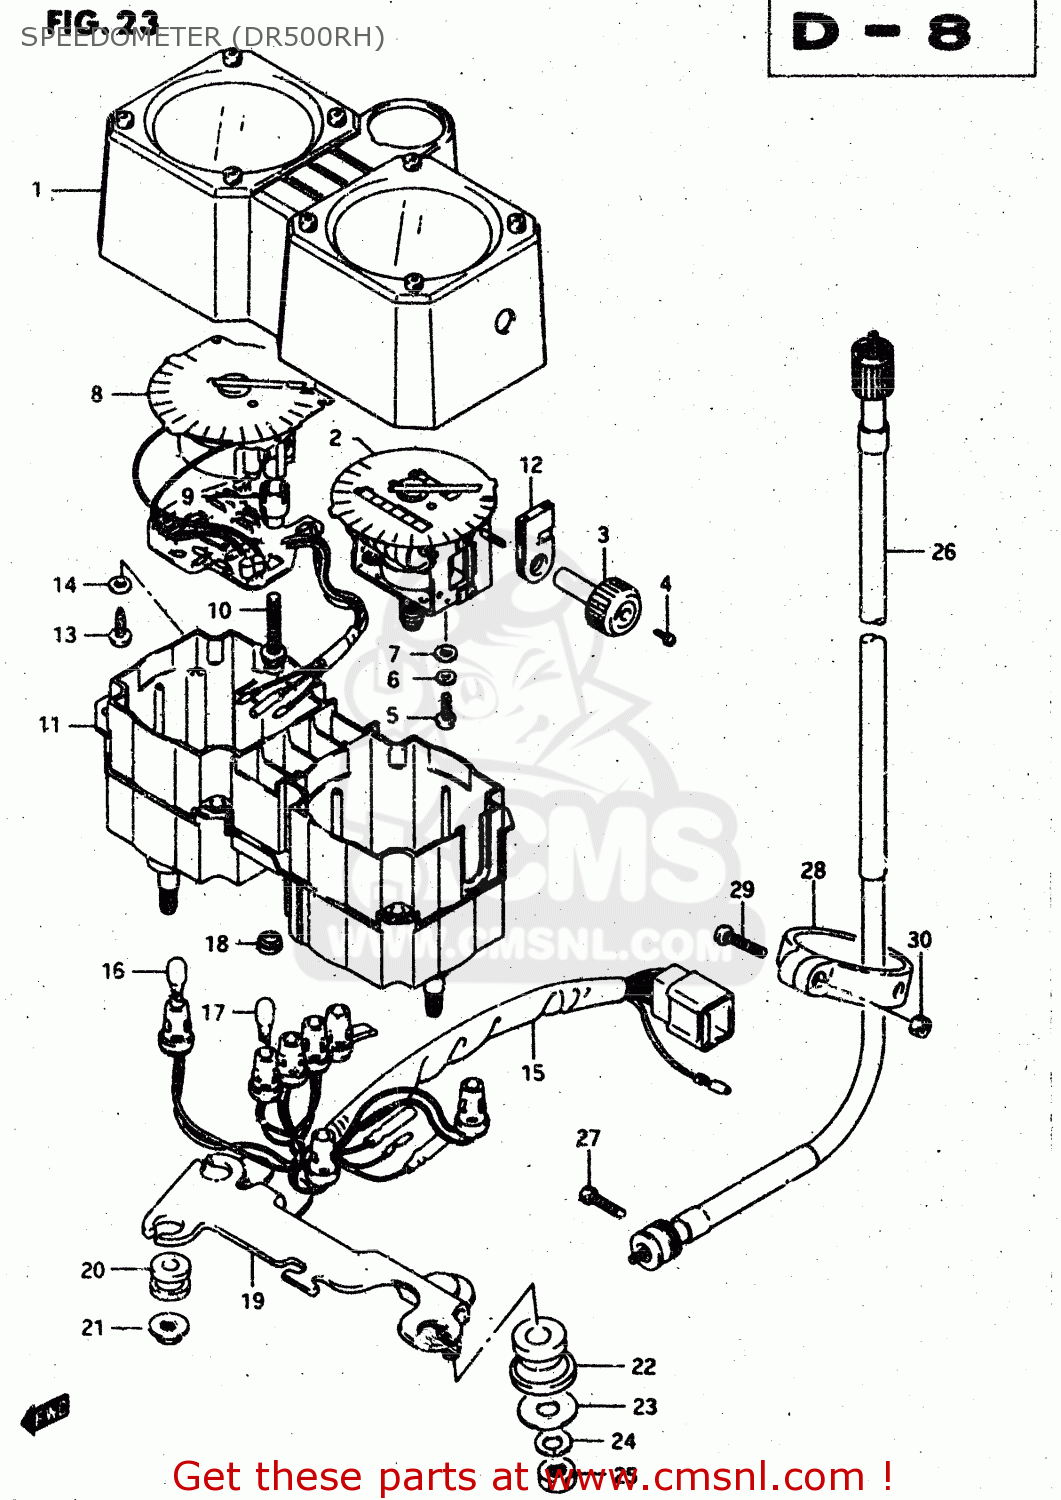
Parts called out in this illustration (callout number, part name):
1	HOOD,METER
2	SPEEDOMETER (KILO)
3	KNOB,TRIP
4	SCREW,TRIP KNOB
5	SCREW
6	LOCK WASHER
7	WASHER 3.3X8X0
8	TACHOMETER
9	SPACER
10	SCREW
11	CASE,METER
12	CUSHION,METER
13	SCREW
14	LOCK WASHER
15	SOCKET,METER
16	BULB(12V1.7W,WB372,T7)
17	BULB(12V3W,WB371,T7)
18	CAP
19	BRACKET,METER
20	CUSHION,METER
21	NUT
22	CUSHION,METER BRACKET
23	WASHER (8.5X20X1.6)
24	WASHER,LOCK,8.
25	NUT
26	CABLE ASSEMBLY,SPEEDOMETER
27	BOLT
28	CLAMP,SPEEDOMETER CABLE
29	SCREW 5X20
30	NUT
